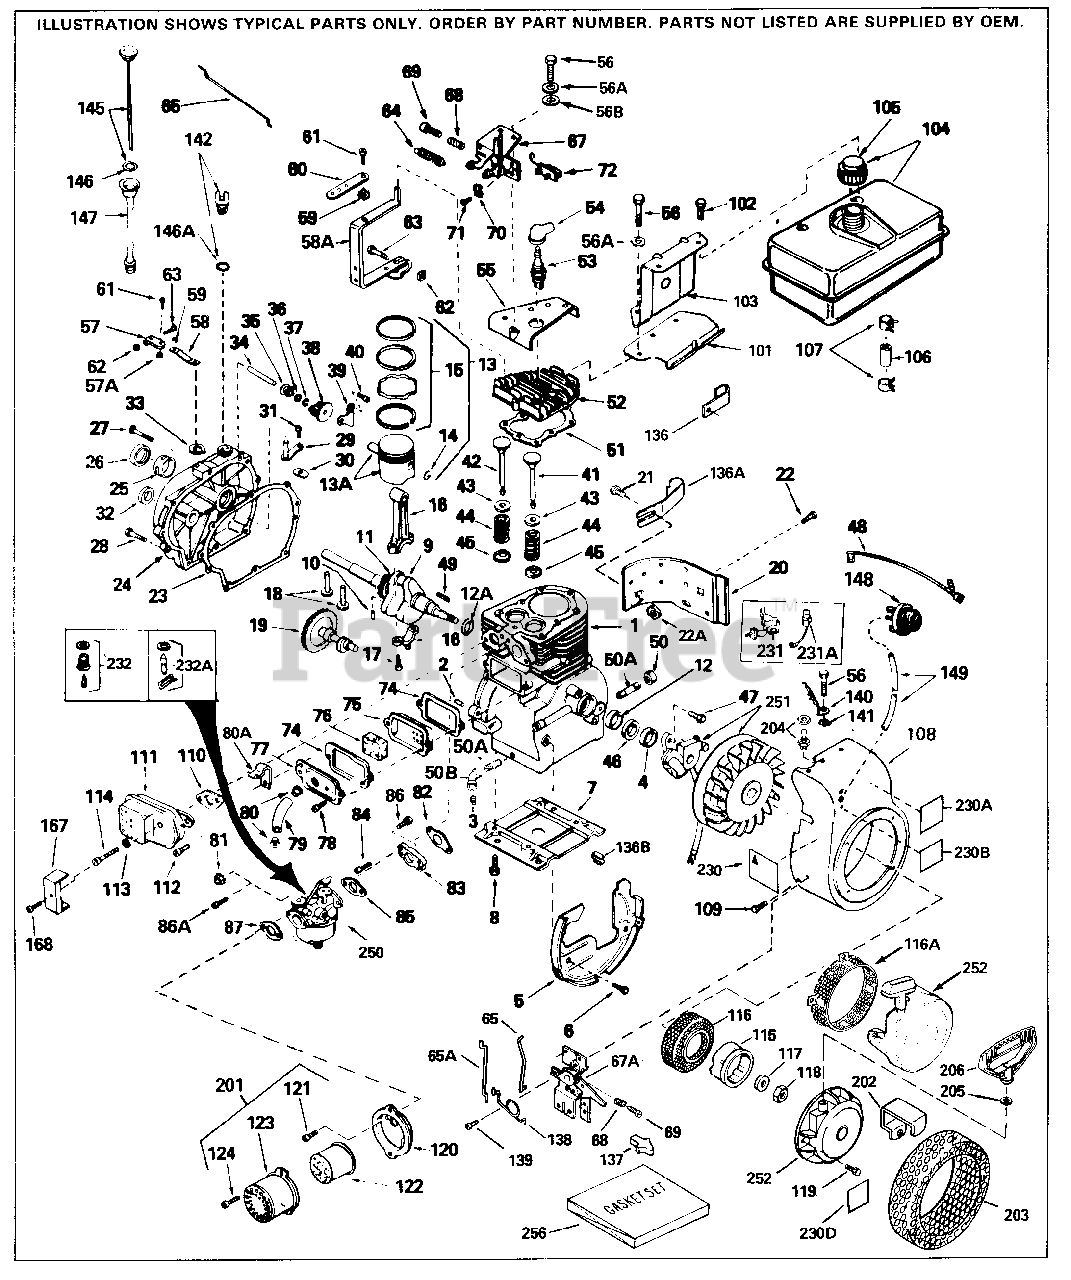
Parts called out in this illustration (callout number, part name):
1	"Cylinder (Incl. 2,3 & 4) 2-5/8" Bore
2	Dowel Pin
3	Oil Drain Plug (Sq. hd., 1/4-18)
4	Seal, Oil
5	Blower Housing Baffle (Without electr ic starter knock out) (Use as require d)
5	Blower Housing Baffle (With electric starter knockout) (As req.)(point ign .)
6	Screw, 1/4-20 x 5/8"
7	Base, Engine mounting
8	Screw, 5/16-18 x 3/4"
9	Crankshaft
10	Pin, Crankshaft gear rod.)
11	Gear, Crankshaft (Used on early produ ction) This gear is serviceable ONLY when it is pinned to the crankshaft.
13	Piston, Pin & Ring Set (Std.) 2-5/8" Bore
13	Piston, Pin & Ring Set (.010" OS)
13	Piston, Pin & Ring Set (.020" OS)
13A	Piston & Pin Ass'y. (Std.)(2-5/8") In cl. 14
13A	Piston & Pin Ass'y. (.010" OS) Incl. 14
13A	Piston & Pin Ass'y. (.020" OS) Incl. 14
14	Piston Pin Retaining Ring
15	Ring Set (Std.) (2-5/8" Bore)
15	Ring Set (.010" OS)
15	Ring Set (.020" OS)
16	Rod Assy., Connecting (Incl. 17)
17	Bolt, Connecting rod (Incl. 2 pieces)
18	Lifter, Valve
19	Camshaft (Extended)
20	Extension, Blower housing
21	Screw, 10-24 x 1/2"
22	Screw, T-30, 1/4-20 x 1/2"
22	Screw, 1/4-20 x 5/8" Use as required
23	Gasket Cylinder Cover
24	Cover, Cylinder (Incl. 26, 32 & 34)
25	Bushing, Crankshaft
26	Oil Seal
27	Screw, 1/4-20 x 1-1/4"
28	Screw, 1/4-20 x 1-3/4"
29	Rod Assy., Governor (Incl. 30 & 31)
30	Yoke, Governor
31	Screw, 6-40 x 5/16"
32	Camshaft Seal
33	Retaining Ring
34	Shaft, Mechanical governor
35	Spool, Governor
36	WASHER
37	Retaining Ring
38	Gear Assy., Governor
39	Bracket, Governor gear
40	Screw, 10-24 x 1/2"
41	Intake Valve (Std.)
41	Intake Valve (1/32" OS)
42	Exhaust Valve (Std.)(Incl. 151)
42	Exhaust Valve (1/32" OS) (Incl. 151)
43	Valve Spring Cap
44	Valve Spring
45	Cap, Lower valve spring
46	Gasket, Stator
47	Screw, 1/4-20 x 5/8"
48	Ground Wire
49	Key, Flywheel
50	Cap, Oil drain
50A	Nipple, Oil drain 1/4" x 2-1/2"
51	Gasket, Cylinder head
52	Head, Cylinder
53	Resistor Spark Plug (RJ-17LM)
54	Cover, Spark plug (Use as required)
55	Cover Assy., Cylinder head
56	Screw, 5/16-18 x 2" (Use as required)
56	Screw, 5/16-18 x 2-1/4" Use as requir ed
56	Screw, 5/16-18 x 2-1/2" Use as requir ed
56A	Washer, Flat (Use as required)
56B	Washer, Belleville (Use as required)
57	Governor Lever Clamp
57A	Lock Nut, 8-32
58	Lever Assy., Governor
59	Lock Washer #8
61	Screw, 8-32 x 5/16"
62	Lock Nut, 10-32
63	Screw, 10-32 x 3/4"
65	Link, Throttle
65A	Link, Governor
67A	Control Bracket Incl. 68, 69, 72 & 1 38
68	Spring, Compression
69	Screw, 5-40 x 7/16"
70	Conduit Clip
71	Screw, 10-32 x 3/8"
72	Terminal Assy. (Use as required)
74	Valve Cover Gasket
75	Breather Body
76	Breather Element
77	Valve Cover
78	Screw, 10-24 x 1/2"
79	Breather Tube
82	* Gasket, Intake pipe to cylinder
83	Flange, Carburetor (Incl. 86A)
84	Screw, 5/16-18 x 3/4"
85	* Gasket, Carburetor
86A	Screw, 1/4-20 x 13/16"
87	* Air Cleaner Gasket (Use as required)
87	Spacer, Cleaner (Use as required)
101	Bracket, Fuel tank
102	Screw, 1/4-14 x 7/8"
103	Plate, Fuel tank mounting
104	Fuel Tank (Incl. 105 & 107) NOTE: Th ese tanks were built with different s ize fuel inlet openings. Tanks with t he 1-3/16" I.D. opening use fuel cap 33032 or 34210. Tanks with the 1-1/2 " I.D. opening use fuel cap 35355.
105	Fuel Cap (Red 1-1/2" ID) (also availa ble in Packaged Part #740005B) (Red Plastic) (Spurt resistant, Low profil e) (Use as required)
105	Fuel Cap (Red Plastic) (Spurt resista nt, High profile) (Use as required)
105	Fuel Cap (Red) ed)
105	Fuel Cap (White Plastic)(Std.) As req uired
106	Fuel Line (8.62") equired)
106	Fuel Line (Braided, 32") Use as requi red
107	Fuel Line Clamp
108	Blower Housing (For elec.start) Incl. 164,165
109	Screw, T-40, 5/16-24 x 21/32"
110	* Gasket, Exhaust flange
111	Muffler
112	Screw, 5/16-18 x 3/4"
114	Screw, 5/16 - 18 x 2"
115	Cup, Starter
116	Starter Screen
117	Washer, Belleville
118	Nut, Hex
119	Screw, 1/4-28 x 7/16"
137	Control Knob
138	Spring, Speed control
139	Screw, 10-32 x 1/2"
145	Dipstick (Incl. 146)
146	"O" Ring
147	Oil Fill Tube
148	Primer Assy.
149	Line, Primer
201	Air Cleaner Ass'y. (Red Poly)(Incl. 8 7,120,121,122,123,124 & 230)(As req.)
201	Air Cleaner Kit, Mini bike (Incl. 87, 120,121,122,123 & 124) (Use as requir ed)
230	Decal, Instruction
230B	Decal, Primer
231	Breaker Points (also available in Pac kaged Part #740037B) tion)
231A	Condenser (also available in Packaged Part #740037B)
232A	Inlet, Needle Seat & Clip Assy.
250	Carburetor (Incl. 85) (Refer to Divis ion 5, Section A, Page 140 for breakd own)
251	Magneto (w/ring gear) NOTE: The comp lete magneto is not available as an a ssembly. The magneto number is shown for reference purposes only. Order component parts individually, as show n in parts list. (Refer to Division 5 , Section B, page 39 for
252	Rewind Starter Refer to Division 5, S ection C, page 29 for breakdown
256	Gasket Set (Incl. items marked*)
